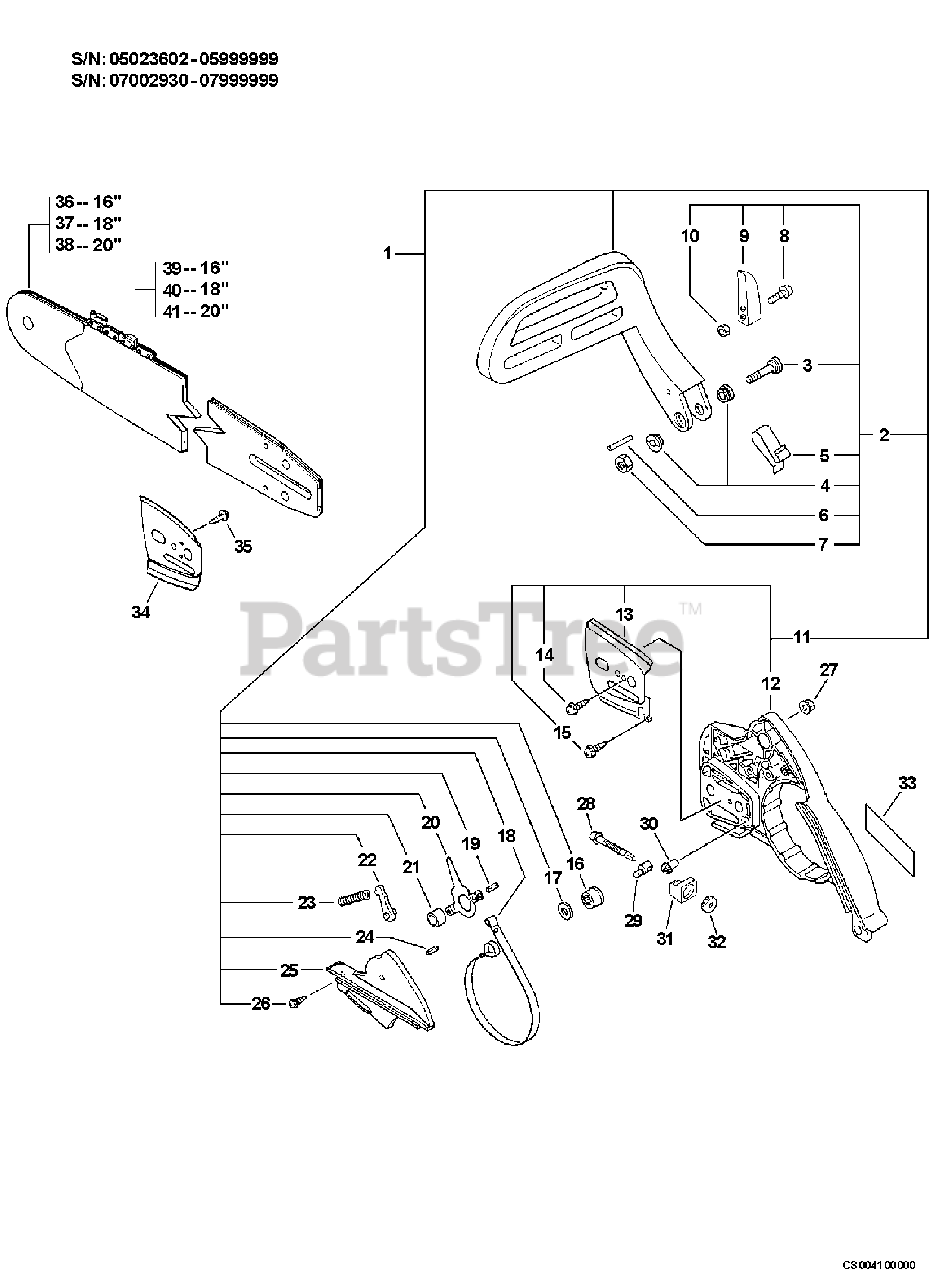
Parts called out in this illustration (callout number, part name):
1	CHAIN BRAKE ASSY
2	BRAKE LEVER ASSY
3	SCREW 5×32
4	COLLAR 5.3×10×13×L5
5	SPRING, FLAT
6	PIN 3×26
7	NUT, LOCK M5
8	SCREW 4×18
9	WEIGHT, BRAKE
11	SPROCKET GUARD ASSY
12	GUARD, SPROCKET
13	PLATE, GUIDE - OUTER
14	SCREW 3×6
15	SCREW 4×10
16	ADJUSTER, BRAKE
17	WASHER 8
18	BAND, BRAKE
19	PIN, SPRING 4×8.8
20	LEVER, BRAKE
21	WASHER 5.2×12×14
22	STOPPER, BRAKE
23	SPRING, COMPRESSION
24	PIN, SPRING 2.5×12
25	COVER, BRAKE
26	SCREW 4×10
27	NUT, FLANGE M8×1.25
28	SCREW, CHAIN TENSION
29	TENSIONER, CHAIN
30	GEAR, BEVEL
31	COLLAR 8
32	GEAR, BEVEL
33	LABEL - ECHO
34	PLATE, GUIDE - INNER
35	SCREW 4×6
36	GUIDE BAR - 16" -- DOUBLE GUARD
37	GUIDE BAR - 18" -- DOUBLE GUARD
38	GUIDE BAR - 20" -- DOUBLE GUARD
39	SAWING CHAIN - 16" -- PRO GUARD
40	SAWING CHAIN - 18" -- PRO GUARD
41	SAWING CHAIN - 20" -- PRO GUARD
